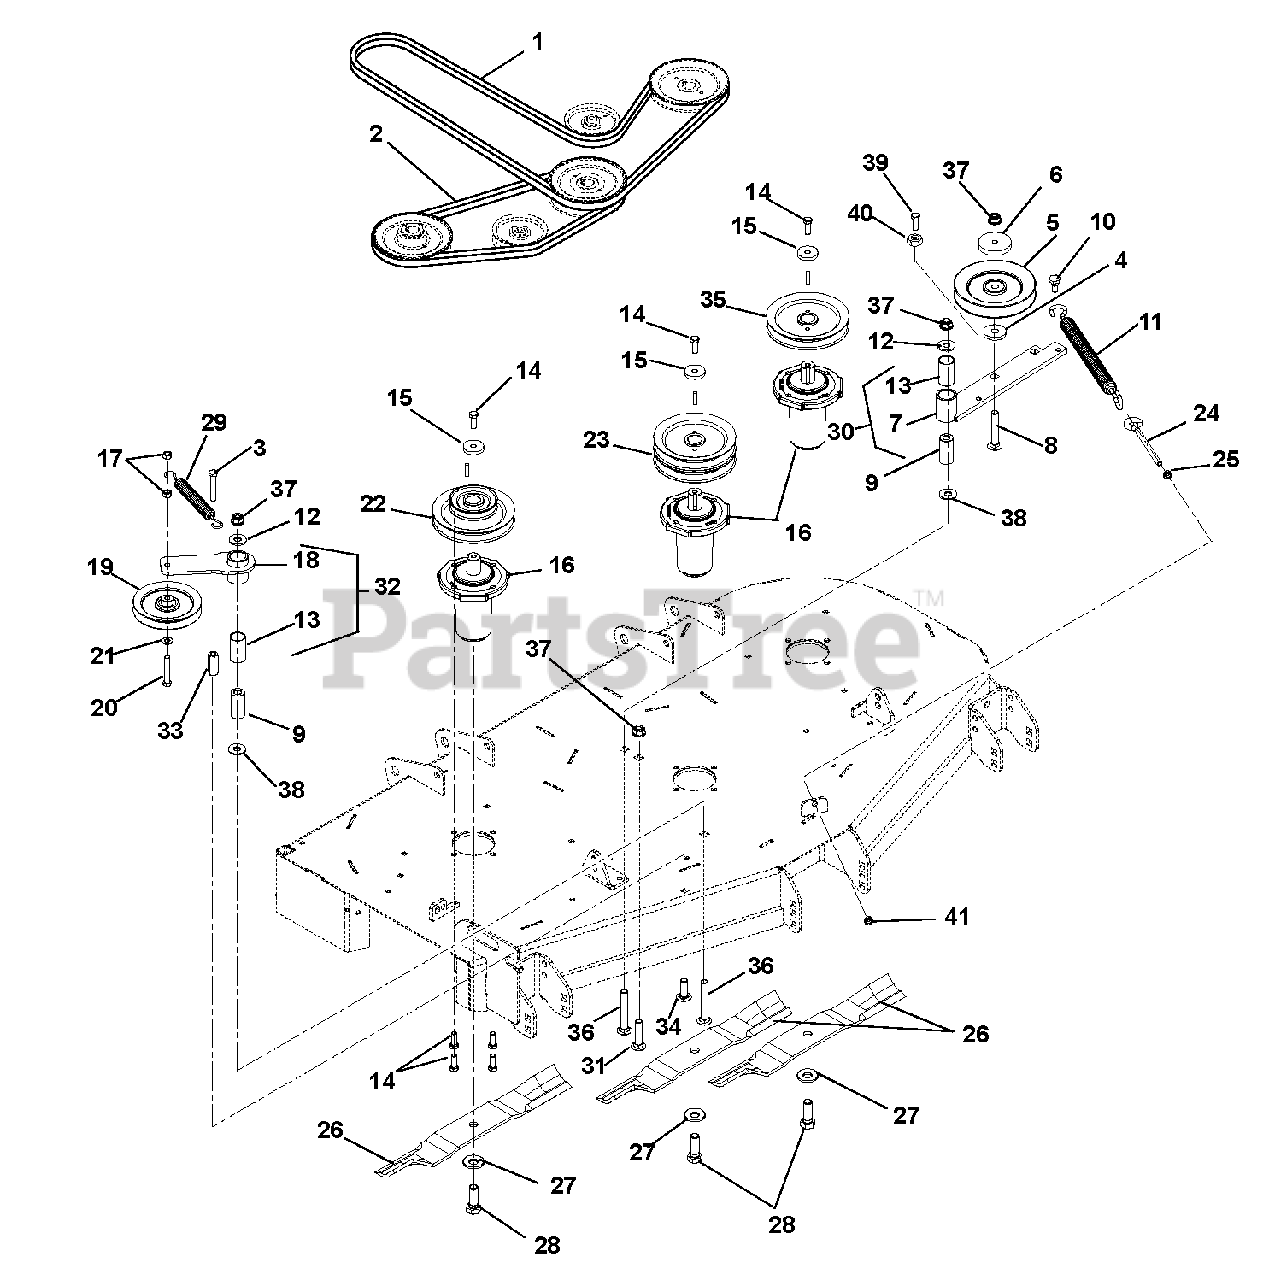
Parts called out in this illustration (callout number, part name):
2	Belt, B 63.00 Raw Cogged (991084)
3	Bolt, Hex .38-16 x 1.50 Grade 5
4	Bushing, Spacer .502 x .997 x .50
5	Sheave, .50" ID x 6.00" OD V-Idler
6	Cap, Idler Bearing Sealing
7	Idler Pivot Arm Weldment- Black
8	Bolt, Round Head Square Neck .50-13 x 3.00 Grade 5
9	Bearing, Pedestal
10	Bolt, Shoulder EP .38-16 x .30 Hex
11	Spring, Extension (Deck Idler)
12	Washer, Flat Steel .563 x 1.38 x.109
13	Bushing, 1.00 x 1.125 x 1.936
14	Bolt, Hex .38-16 x 1.00
15	Washer, Flat Steel .406 x 1.50 x .245
16	Spindle Assembly
17	Nut, Locking, Center .38-16
18	Idler, Pivot Arm
19	Sheave, .38" ID x 5" OD V-Idler
20	Bolt, Hex .38-16 x 2.25
21	Washer, Flat Steel .406 x .812 x .065
22	Sheave, Double 1.0' ID x 6.75" x 4.35" OD (991084)
23	Sheave, Double 1"ID x 6.75"OD (991084)
24	Bolt, .38-16 x 4.00 .62 Diameter Eye
25	Nut, Hex, Jam .375-16
26	Blade, 20.5" (991084)
27	Washer, Bellville .63 x 1.625 x.14
28	Bolt, Hex .62-18 x 1.75 Grade 8
29	Spring, Extension
30	Assembly, PTO Idler Pivot Arm (Includes item 7 and item 13)
31	Bolt, Round Head Square Neck .50-13 x 1.5, Full Thread, Grade 5
32	Assembly, Idler Pivot Arm (Includes item 13 and item 18)
33	Nut, Coupling .375-16 x 1.75
34	Bolt, Round Head Square Neck .38-16 x 1.00
35	Sheave, Single 1" ID x 6.75" OD (991084)
36	Bolt, Round Head Square Neck .50-13 x 3.50 Grade 5
37	Nut .50-13 Nyloc Flange
38	Washer, Flat .640 x 1.75 x .250
39	Bolt, Hex .38-16 x 2.75 Grade 5
40	Nut, Hex .38-16
41	Nut, Locking-Center-Jam .375-16
